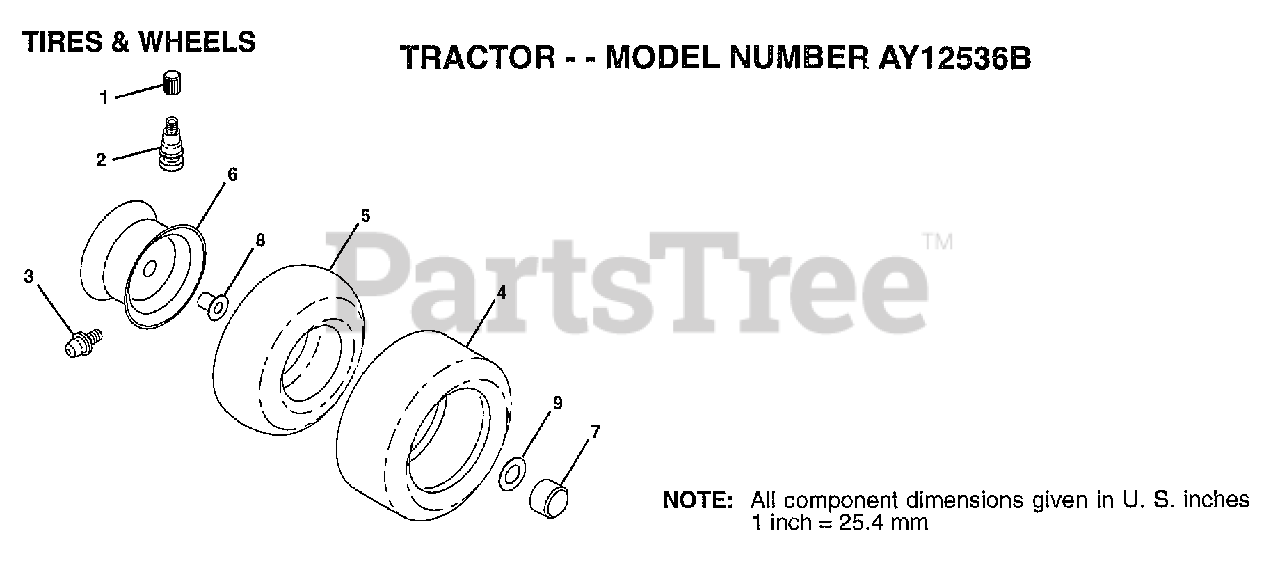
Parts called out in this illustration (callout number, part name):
1	VALVE CAP
2	VALVE STEM LT
3	FITTING LT
5	TUBE.5.3/4.5/6
5	TUBE.16X6.5/7.5-8
6	"RIM FRONT 6"""
6	"RIM ASM REAR 8"""
7	HUB CAP
8	"FLANGE, BEARING"
9	WASHER
